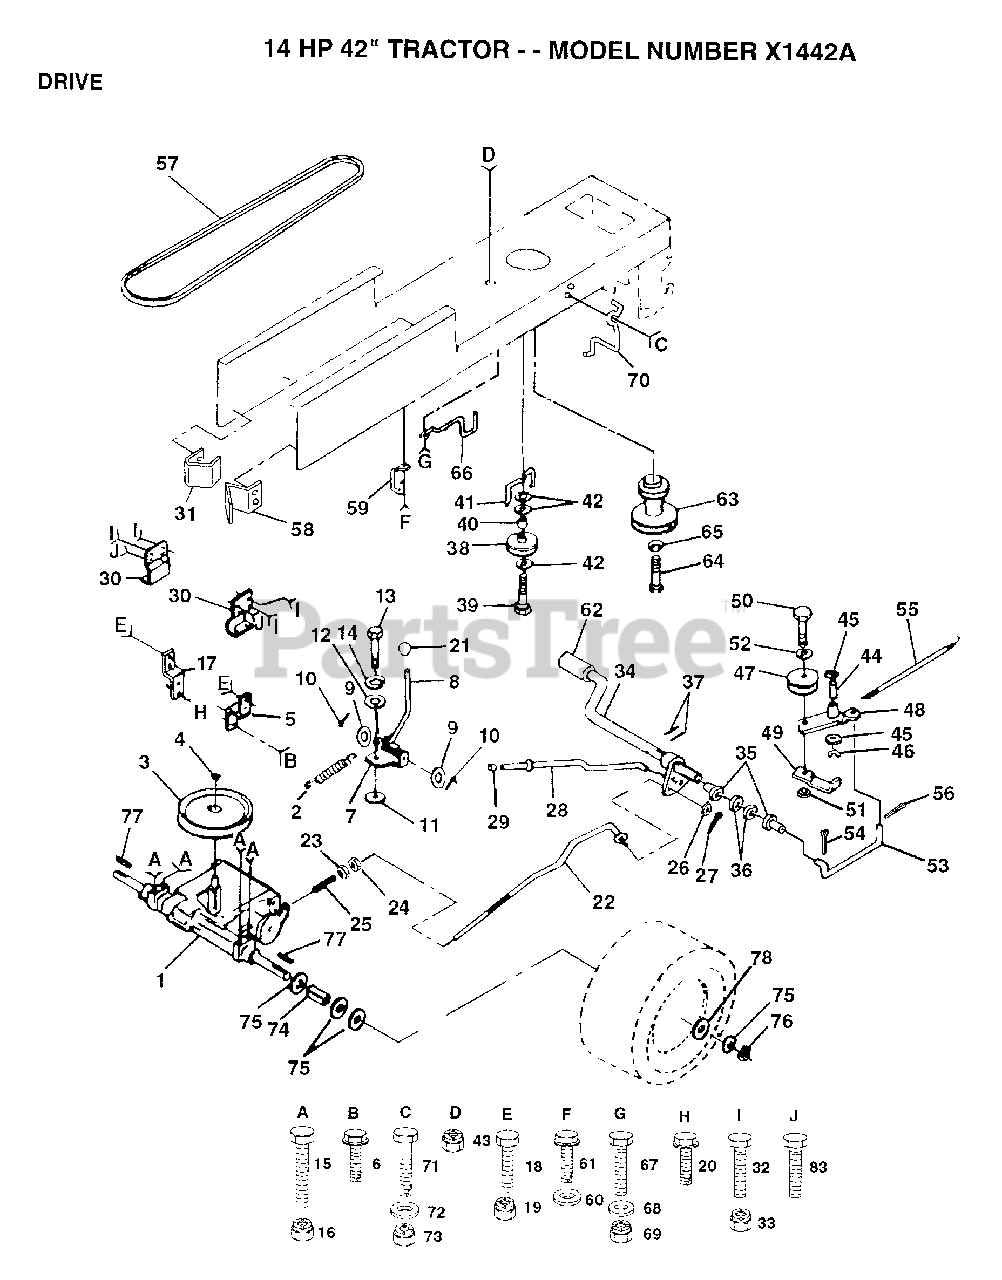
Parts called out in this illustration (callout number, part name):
3	"PULLEY,TRANSAXLE"
5	STRAP TORQUE
6	SCREW
8	SHIFT ROD
9	WASHER
10	PIN COTTER 1/8
11	WASH-SHFT PLT LT
12	WASHER LT
14	LOCKWASHER
15	BOLT
17	STRAP TORQUE
20	SCREW
21	KNOB T (1/2-HOLE)
22	BRAKE ROD
23	NUT
24	NUT
25	SPRING ROD LT
26	WASHER
27	COTTER PIN
28	BRAKE PARK ROD
29	PLUNGER CAP T
30	TRANSAXLE MTG BKT
31	"KEEPER,BELT LH"
32	BOLT
35	NYLON BEARING
36	WASHER LT
38	PULLEY.IDLER.FLAT
39	BOLT
40	SPACER T
41	BELT KEEPER LT
42	WASHER
44	"LY, BEARING"
45	WASHER LT
46	KLIP RING
48	ARM IDLER
49	RETAIN BELT
52	WASHER
53	"LINK, CLUTCH T"
54	COTTER PIN
55	"SPRING, RETURN LT"
56	COTTER PIN
57	BELT-V
58	"KEEPER,BELT RH"
60	WASHER
61	SCREW
62	PEDAL COVER T
64	BOLT
65	LOCKWASHER
66	KEEPER.BELT.ENG.L
67	BOLT
68	WASHER
70	KEEPER BELT ENG
71	BOLT
72	WASHER
74	SPACER LT
75	WASHER
76	E-RING LT
77	SQUARE KEY
78	WASHER
83	SCREW
